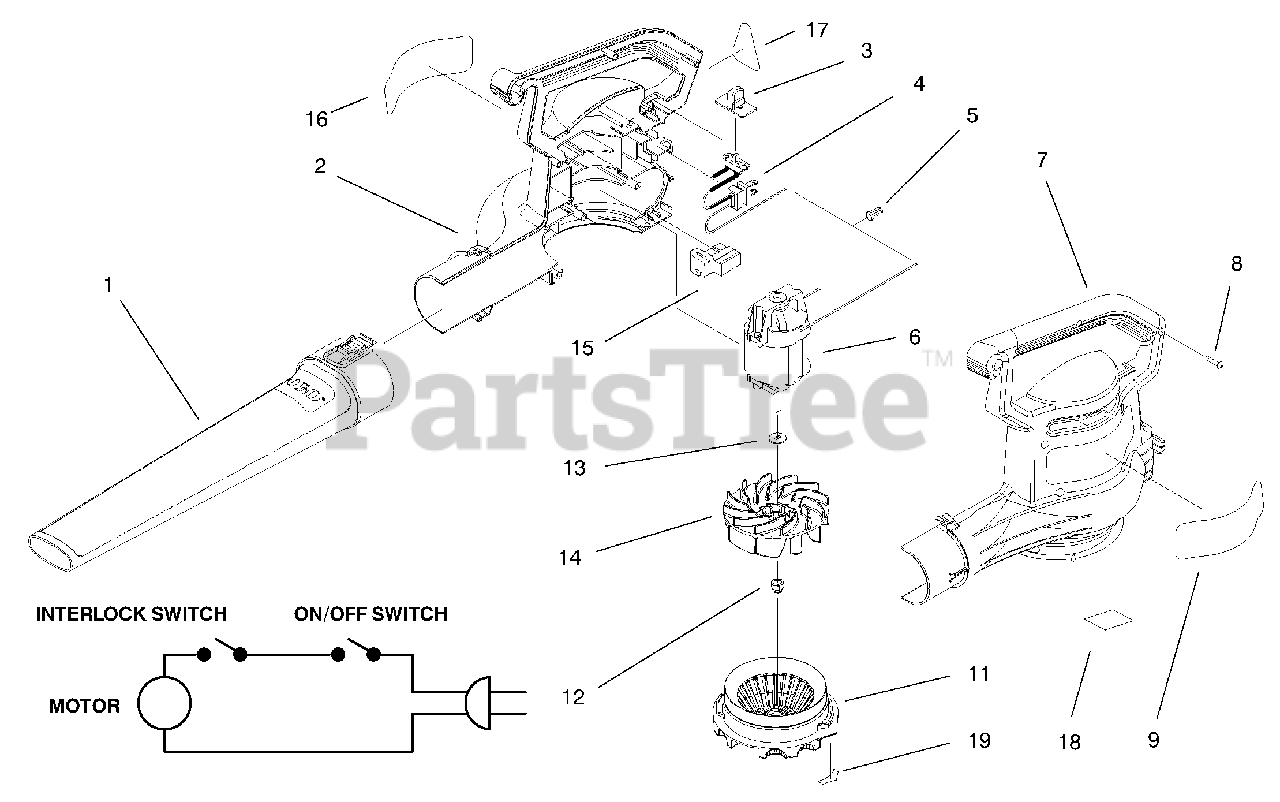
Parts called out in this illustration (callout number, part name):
1	Tube-Blower
2	Housing-R.H.
3	Cover-Switch
4	Harness Assembly
5	Connector-Wire Nut
7	Housing-L.H.
8	Screw-Phillips Hd. Tap.
9	Decal-Logo
11	Cover-Inlet
12	Nut-Cap Hex
14	Impeller
15	Switch-Interlock
16	Decal-Warning
17	Decal-Information
18	Decal-Alignment, Housing
19	Decal-Alignment, Cover
